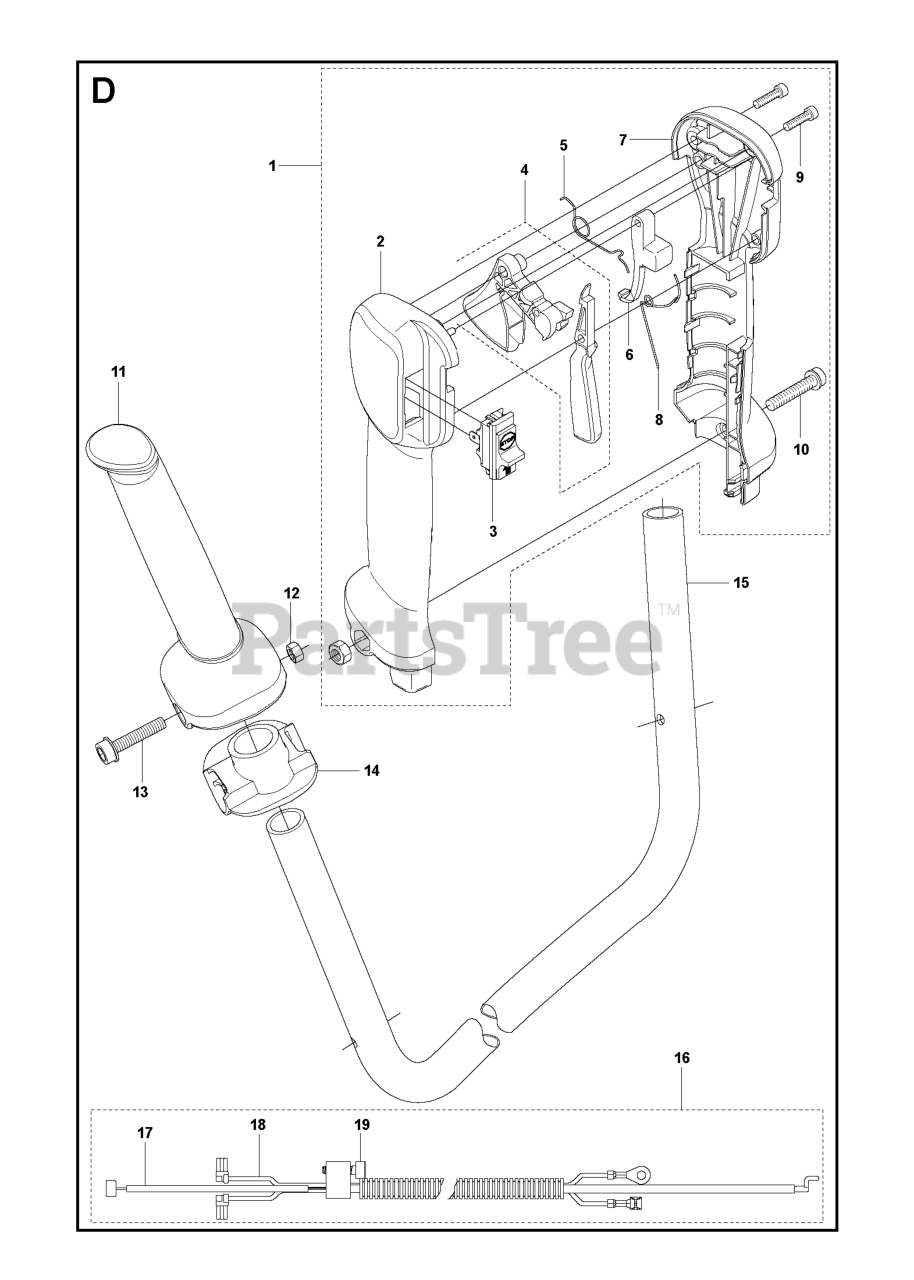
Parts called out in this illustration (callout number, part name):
1	HANDLE SYSTEM ASSY.
3	STOP BUTTON
4	THROTTLE CONTROL
6	LOCKOUT STARTER THROTTLE
10	SCREW
16	WIRING KIT COMPLETE
17	THROTTLE WIRE
18	SHORT CIRCUIT CABLE
